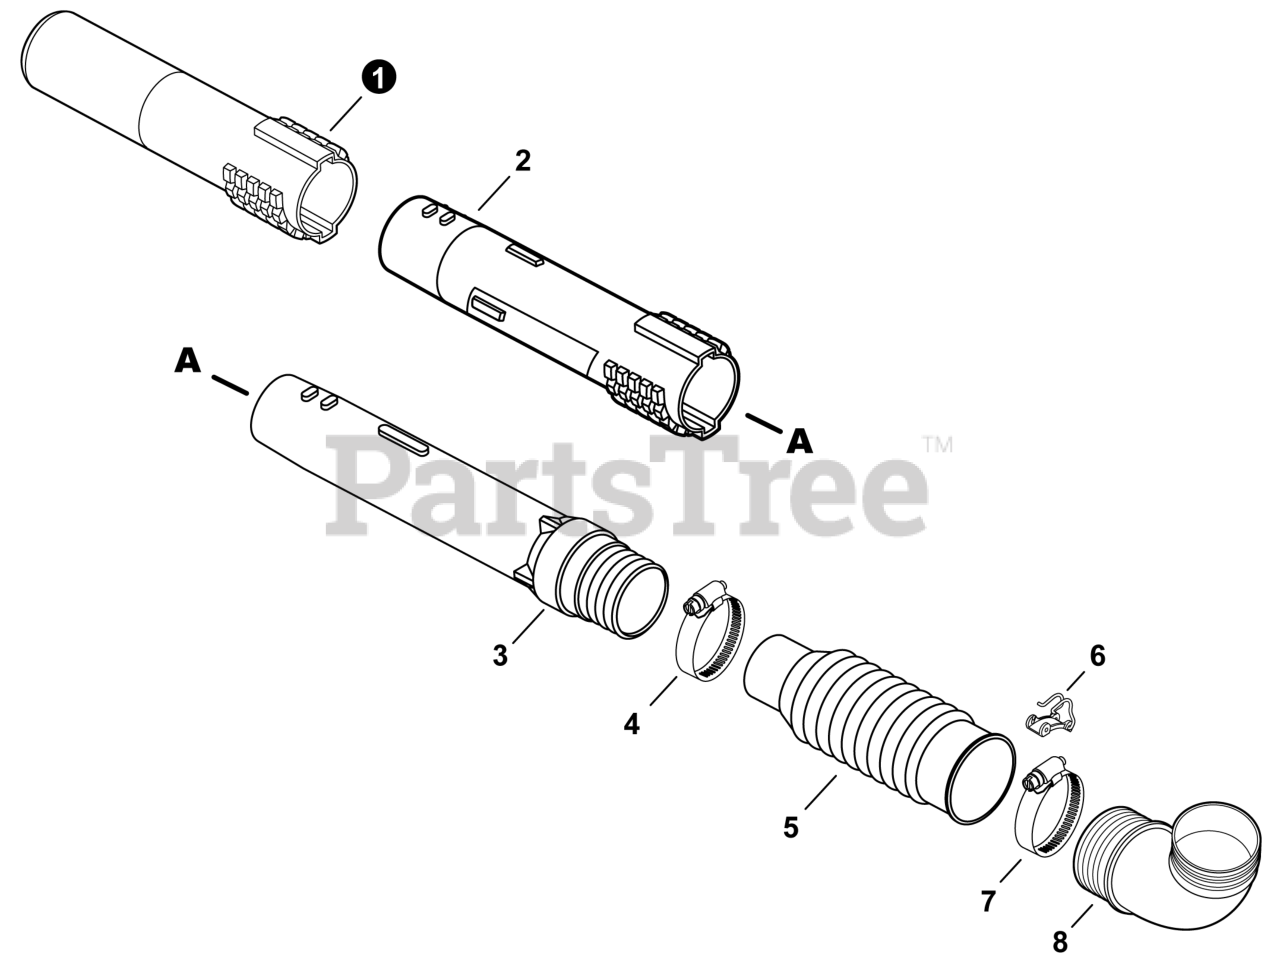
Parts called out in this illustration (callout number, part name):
1	TUBE, BLOWER - NOZZLE
2	TUBE, BLOWER - STRAIGHT
3	TUBE, BLOWER - SWIVEL
4	CLAMP - BAND 58.7 MM / 82.5 MM
5	TUBE, BLOWER - FLEXIBLE
6	CLIP, CABLE
7	CLAMP - BAND 78 MM / 103 MM
8	TUBE, BLOWER - ELBOW
